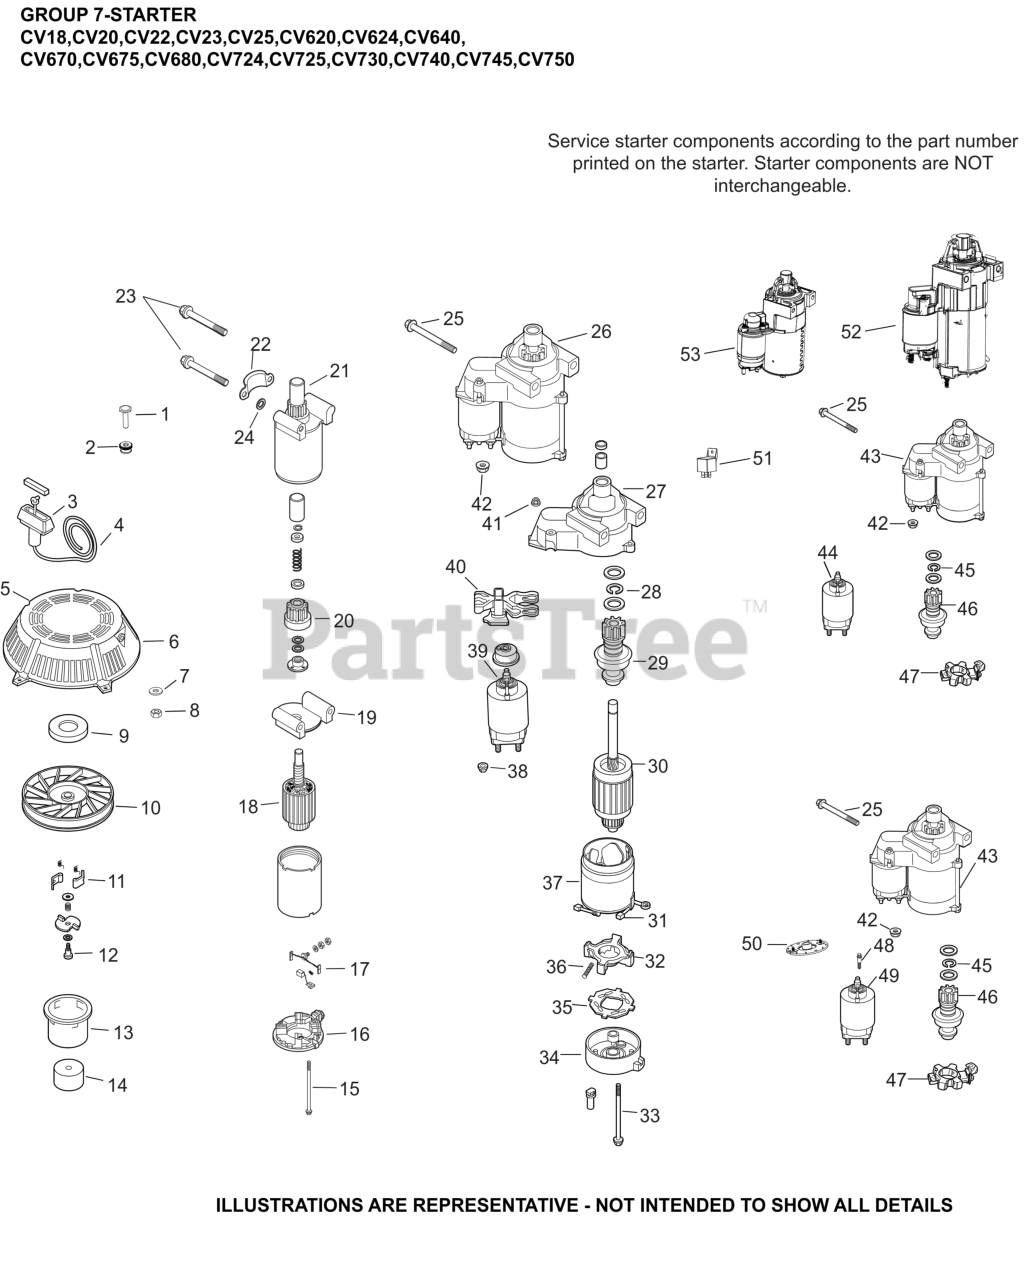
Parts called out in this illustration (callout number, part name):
25	SCREW, FLG M8X1.25X80
42	NUT, FLG M8X1.25
43	STARTER, SOLENOID SHIFT-(#2509824S)
